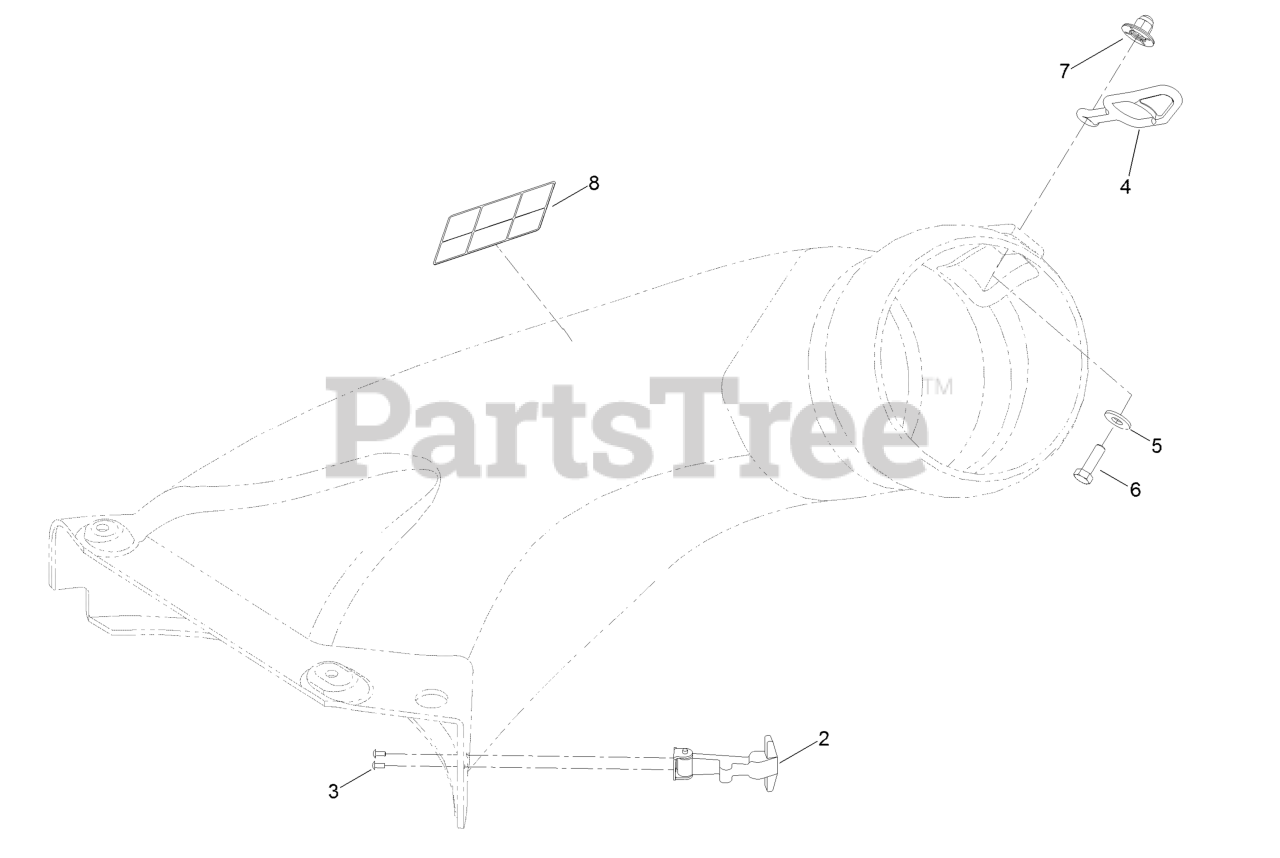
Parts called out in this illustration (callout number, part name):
2	HANDLE ASM
3	RIVET-POP
4	RETAINER-DUCT
5	WASHER-FLAT
6	SCREW-HH
7	NUT-IMPELLER
8	DECAL-DANGER
